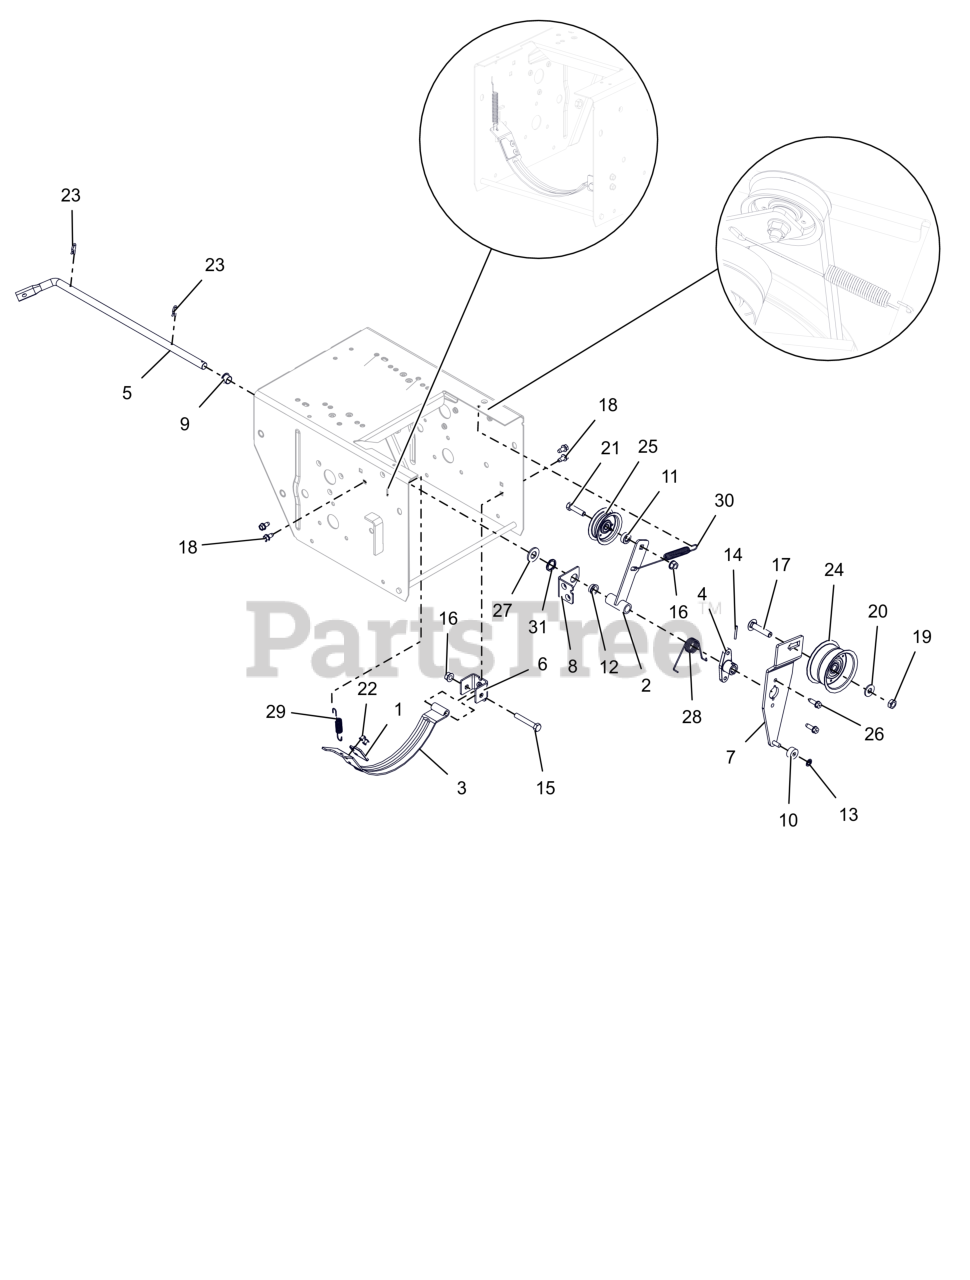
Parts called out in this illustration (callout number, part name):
1	PAD, BRAKE
2	ARM, IDLER-TRACTION
3	ARM, BRAKE-ATTACHMENT
4	HUB, BRAKE ARM
5	ARM, ATTACHMENT
6	PIVOT, BRAKE
7	ARM, IDLER - ATTACHMENT
8	BRACKET, SUPPORT
9	BUSHING, POLYLINER-.50 SPLIT
10	BSHG,SLV .265 X .625 X .375
11	SPCR, BRG .315X.500X.358X.281
12	BSHG,FLANGE .500X.625X.270X.75
13	RG-RTNG-EXT .250X.010
14	PIN-ROLL .125X1.00
15	BLT, HEX .31-18X2.00 G5 ZCC
16	NUT-LK-TOP-FLG .312-18 GF ZCC
17	BLT, RHSSN .38-16X1.75 G5 ZCC
18	SCR-TAP .25-20X.50 HWH ZCC
19	NUT-LK-CTR-JAM .375-16 GB ZCC
20	WSHR,FLT .375X.875X.083 ZCC
21	BLT, HEX .31-18X1.25 G5 ZCC
22	RVT, POP .1875 ZCC
23	CLIP, SPRING
24	IDLER, FLANGE -2.75 OD X .375 ID
25	IDLER, FLAT - 2.00"
26	SCR,TAP .25-20X.75 HWH TR ZCC
27	WSHR,FLT .531X1.062X.095 ZCC
28	SG-TORS .067X.88
29	SPRING-EXT .437 X .438 X 2.64
30	SG-TENS .06X.482X5.35
31	WAVE SPRING .600X.875X.25FH
